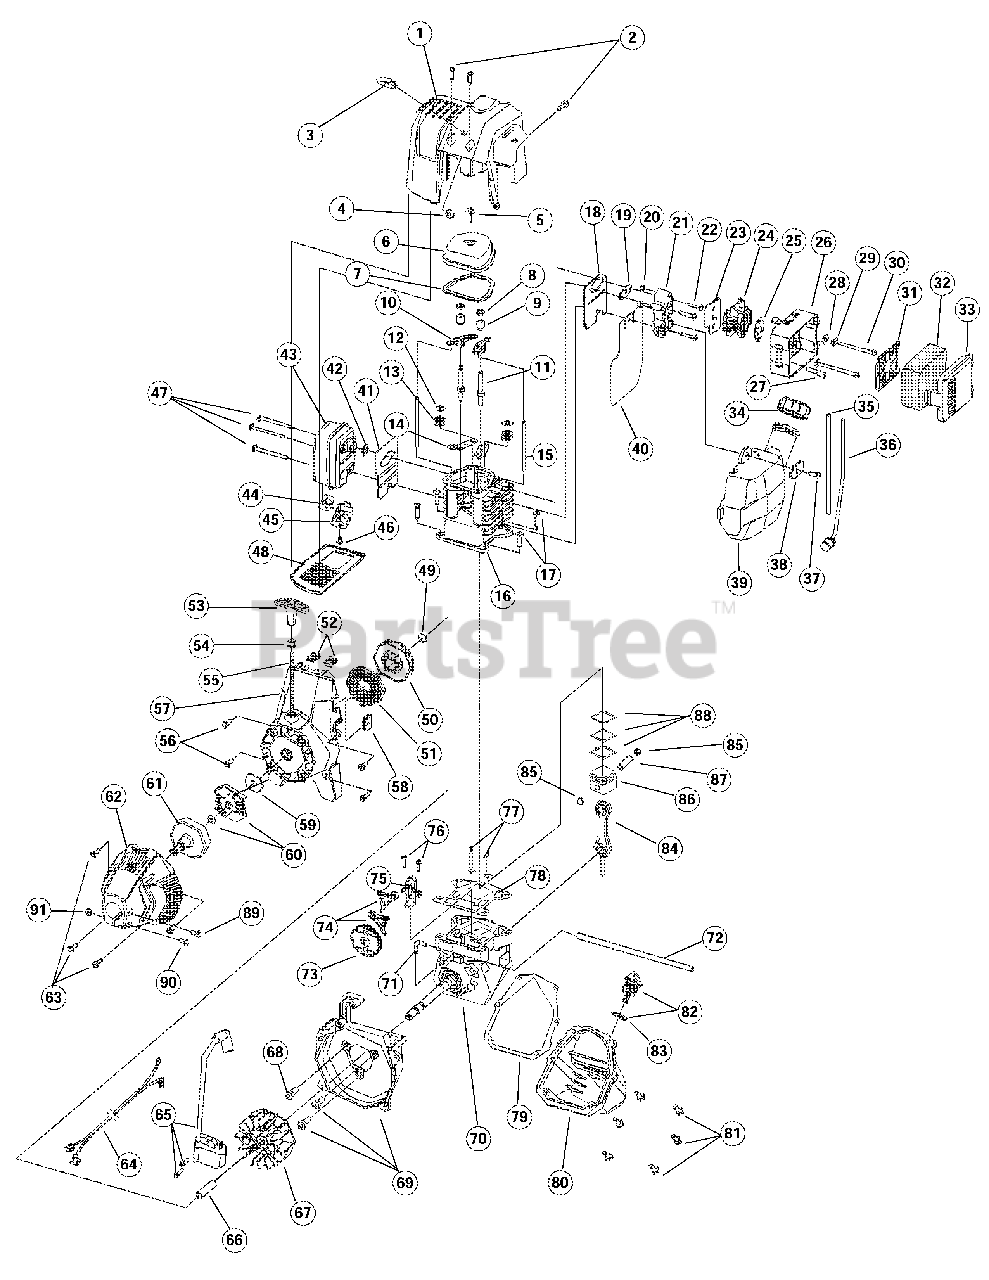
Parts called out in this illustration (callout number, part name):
1	Engine Cover
2	Engine Cover Screws
3	Starter Rope Eyelet
4	Eyelet Nut
5	Valve Cover Screw
6	Valve Cover
7	Valve Cover Gasket
8	Rocker Adjustment Nut
9	Rocker Arm Pivot
10	Rocker Arm
11	Rocker Arm Stud
12	Valve Spring Retainer
13	Valve Spring
14	Push Rod Guide
15	Push Rod
16	Cylinder Assembly (includes 11-14)
17	Cylinder Screw
18	Intake Baffle
19	Carburetor Mount Gasket
20	Nut
21	Carburetor Mount (includes 20)
22	Carburetor Mount Screw
23	Carburetor Gasket
24A	Carburetor w/Primer
24B	Carburetor w/Primer
25	Air Filter Gasket
26	Air Filter Cover Assembly (includes 27, 28, 31-33)
27	Breather Tube Assembly
28	Grommet Washer
30	Air Filter Mounting Screw
31	Air Filter Plate
32	Air Filter
33	Air Filter Cover
34	Fuel Cap
35	Fuel Return Line
36	Fuel Pick-Up Line with Filter
38	Washer
39	Fuel Tank Assembly (includes 34-36)
40	Fuel Tank Shield
41	Muffler Baffle
42	Muffler Gasket
43	Muffler (includes 42, 44-46)
44	Spark Arrestor Screen
45	Screen Cover
47	Muffler Mounting Screw
48	Muffler Cover
49	Pulley Retainer Assembly
50	Recoil Pulley
51	Recoil Spring Canister
52	Nut Clip
53	Pull Handle
54	Rope Guide
56	Starter Housing Screw
57	Starter Housing Assembly (includes 49-56)
58	Wire Grommet
59	Clutch Washer
60	Clutch with Washer
61	Clutch Drum
62	Clutch Cover
63	Clutch Cover Screw
64	Lead Wire
65	Ignition Module with Screws
67	Flywheel
69	Shroud Assembly with Screws (includes 68)
70	Crankcase Assembly (includes 71 & 72)
71	90° Elbow
72	Breather Hose
73	Cam Gear
74	Cam Follower
75	Cam Bracket
76	Cam Bracket Screw
77	Valves, Intake and Exhaust
78	Cylinder Gasket
79	Oil Pan Gasket
80	Oil Pan (includes 79 & 81)
81	Oil Pan Screw
82	Dipstick Assembly (includes 83)
84	Connecting Rod
85	Wrist Pin Button
86	Piston
87	Wrist Pin
88	Piston Ring Set
89	Anit-Rotation Screw
90	Screw
